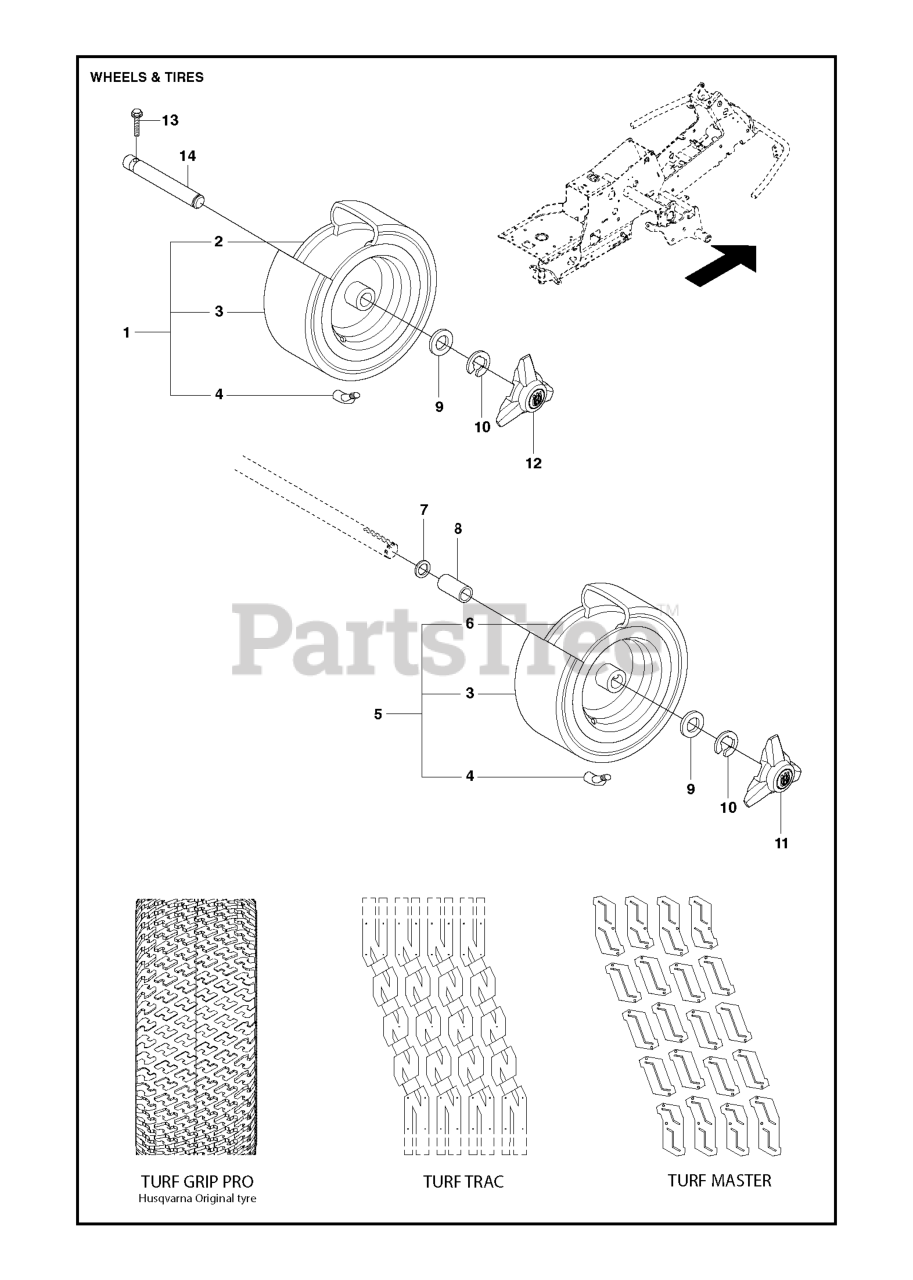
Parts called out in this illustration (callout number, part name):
1	RP WHEEL.STEER.HUSQ.PREM.OVMLD
2	AXLE.CAST.IRON
4	SPINDLE.ASM.LH.16"TIRE.CE
5	SPINDLE.ASM.RH.16"TIRE.CE
6	THRUST WASHER
9	CAP.SPINDLE.BLACK
14	WASHER, LOCK 3/8
15	NUT CROWNLOCK 3/8-24
16	SHAFT.STEER.STEALTH.DD
19	PLATE.STEER.DDL.NLT/NG
21	ADAPTER, WHEEL STNG..
22	BUSHING.ASM.STEERING.A
26	RP INSERT.CAP.WHL.STRG.HUSQ.
28	SCREW, 3/8-16X3/4
35	GEAR.SECTOR.PLATE.DDL.
45	WASHER 9/16"ID, 2 3/8"OD
51	NUT.HEX.1/2-20
53	WASHER.HARDENED
57	BRKT.UPSTOP.GT/LT.TEX
58	BOLT.SHOULDER.SECTOR.P
59	WASHER.THURST.SECTOR.S
60	NUT FLANGE LOCK 5/8-11
61	DRAGLINK.LH.BALLSTUD.D
62	DRAGLINK.RH.BALLSTUD.D
63	SCREW
64	RETAINER.CLIP.SPRING.S
66	BOLT HEX FGHD 7/16-14 X 3 SERR
67	BUSHING.PM.FRONT AXLE
68	NUT.LOCK.FLANGE.7/16
69	WASHER.1.5X.505X.118
70	BRKT.DECK.SUSPENSION.F
118	BUSHING, AXLE CAST
228	DECAL.WHEEL.STRG.LGN.H
